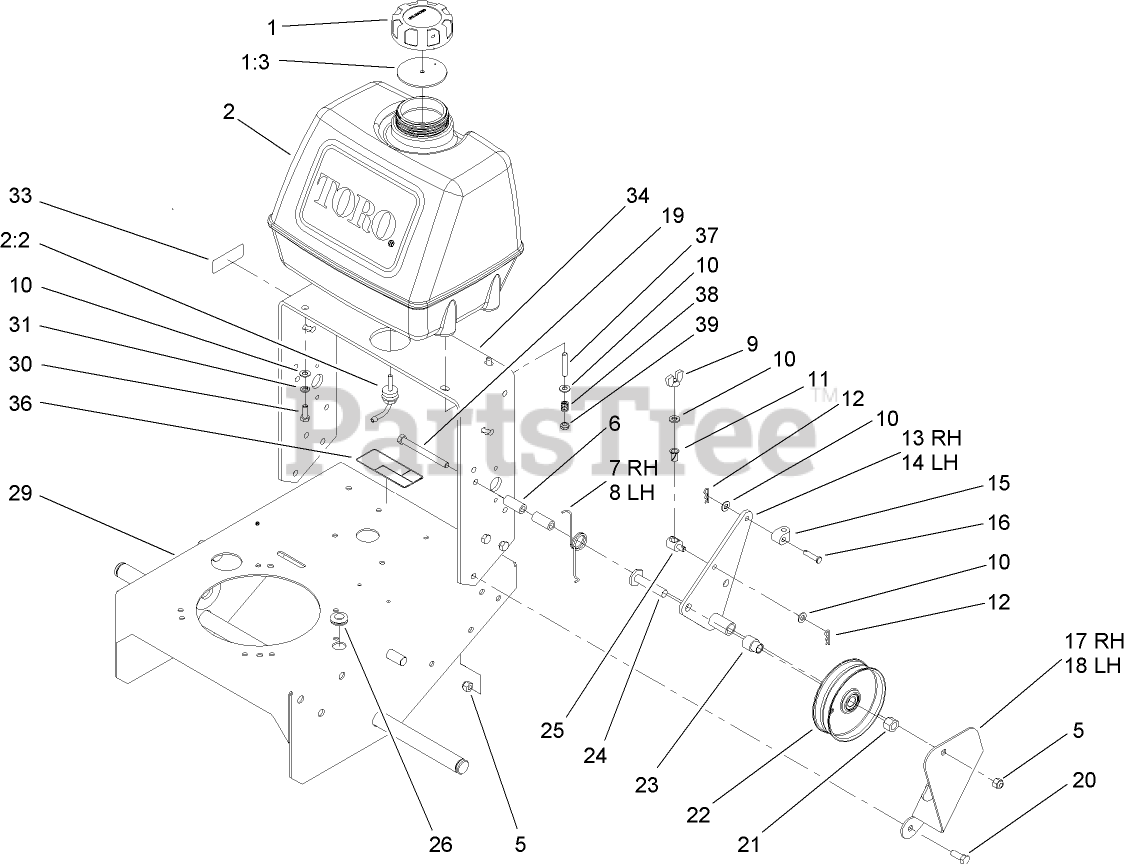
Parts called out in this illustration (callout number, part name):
1	GAS CAP ASM
1:3	GASKET-CAP, GAS
2	FUEL TANK ASM
2:2	FITTING-FUEL, BULKHEAD
5	NUT-LOCK, NI
6	SPACER-PIVOT, IDLER
7	SPRING-TORSION, RH
8	SPRING-TORSION, LH
9	NUT-WING
10	WASHER-PLAIN
11	BUSHING-NYLON
12	PIN-COTTER
13	ARM-IDLER, RH
14	ARM-IDLER, LH
15	FITTING-ROD
16	PIN-CLEVIS
17	BRACKET-SUPPORT, RH
18	BRACKET-SUPPORT, LH
19	SCREW-HH
20	SCREW-HH
21	NUT-LOCK, NI
22	PULLEY-IDLER
23	SPACER-PULLEY
24	SCREW-LEVELER
25	FITTING-ROD
26	GROMMET
29	Frame ASM
30	SCREW-HH
31	WASHER-LOCK
33	DECAL-SHUT OFF, FUEL
34	FRAME-UPPER
36	DECAL-CAUTION
37	STUD-THREADED
38	SPRING-TANK, FUEL
39	NUT-LOCK, NI
